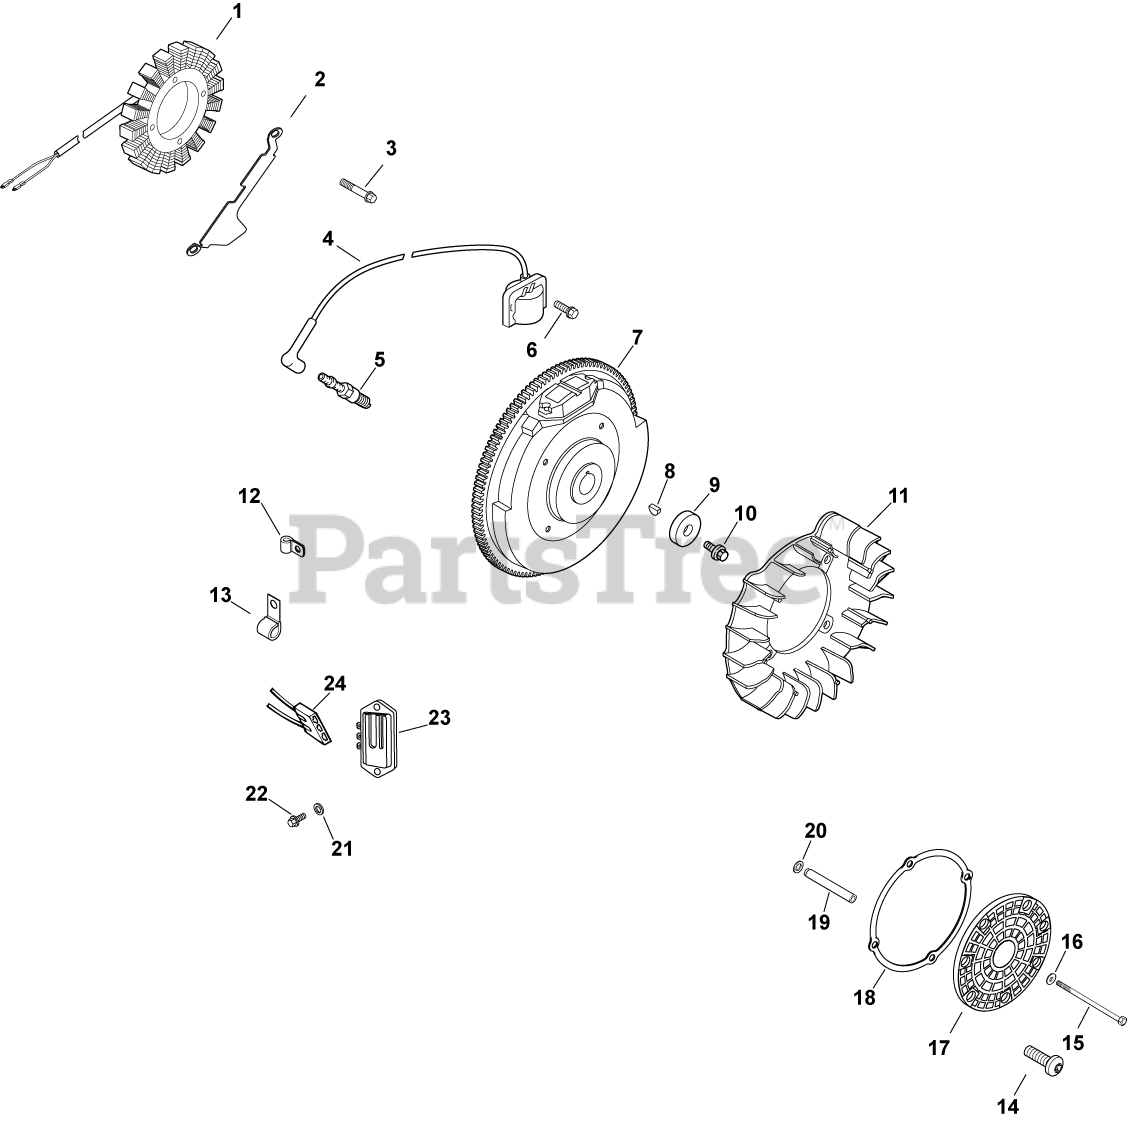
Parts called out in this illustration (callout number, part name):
1	KIT, 15 / 20 AMP STATOR
2	BRACKET, STATOR WIRE
3	SCREW, M5X0.8X25 - (#25086402S)
4	KIT, MODULE IGNTN (CDI FIXED)
5	PLUG, SPARK (PRO SERIES)
6	SCREW, FLG THD FRM M5X.8X20-(#25086399S)
7	FLYWHEEL, PAINTED-USE 24 025 55-S
8	KEY, 3/16" X 5/8"
9	WASHER, FLAT 13/32"
10	SCREW, FLG M10X1.5X45 - (#25086361S)
11	FAN USE 24 157 11-S
12	CLIP, CABLE
14	SCREW, SKT SET #10-24X1/4"
15	SCREW, SOCKET TRUSS HD CAP
16	WASHER, FLAT 1/4" (O.D. 5/8")
17	SCREEN, GRASS
18	RING, SUPPORT USE 25 141 08-S
20	WASHER, SPRING 10 MM
21	WASHER, FLAT 3/16"
22	SCREW, PHL HD #11-16X7/8"
23	REG/RECT-15 AMP (KM)-USE 41 403 10-S
24	CONNECTOR
